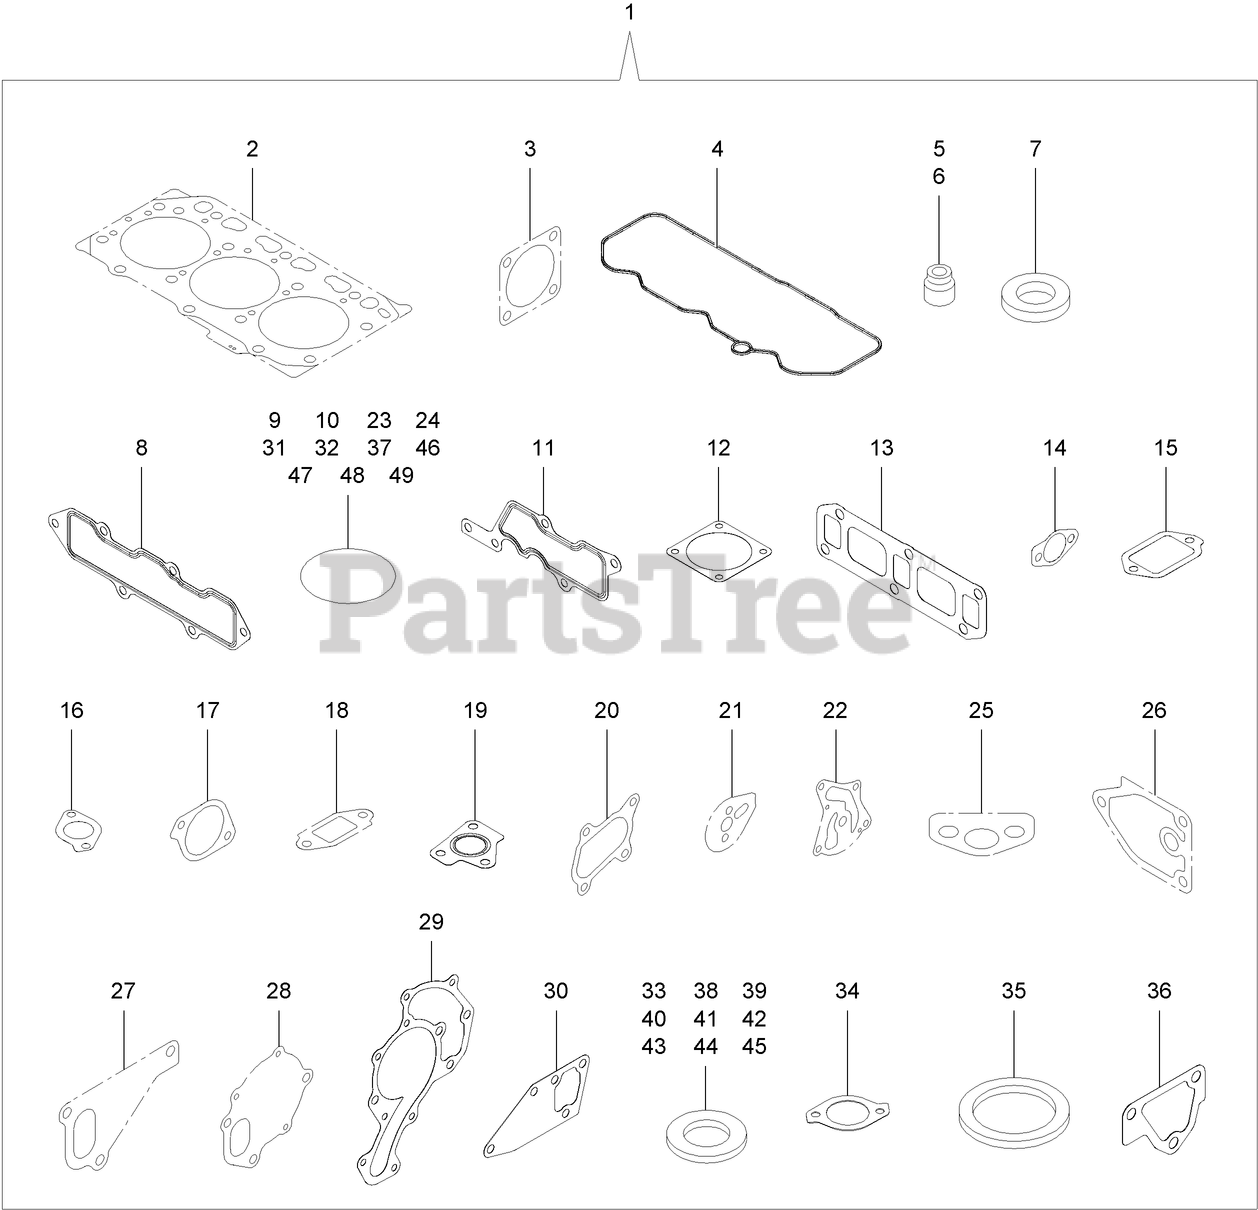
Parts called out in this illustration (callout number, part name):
1	GASKET KIT
2	HEAD GASKET ASM
3	GASKET, PUMP
4	GASKET-COVER, CYLINDER HEAD
5	SEAL-STEM, VALVE
6	SEAL-STEM, VALVE
7	GASKET-INJECTOR
8	GASKET-MANIFOLD, INTAKE
9	O RING-SENSOR, PRESSURE
10	O-RING
11	GASKET-COLLECTOR
12	GASKET-THROTTLE
13	GASKET-MANIFOLD, EXHAUST
14	GASKET-COOLER, E G R
15	GASKET-E G R
16	GASKET
17	GASKET-INTAKE VALVE, E G R
18	GASKET-OUT VALVE, E G R
19	GASKET-IN, T C
20	GASKET-OUT, T C
21	GASKET-IDLE, SHAFT B
22	GASKET
23	O-RING
24	O-RING
25	GASKET
26	GASKET
27	GASKET
28	GASKET
29	GASKET
30	GASKET, WATER PUMP
31	O-RING
32	O-RING
33	GASKET
34	GASKET
35	GASKET
36	GASKET
37	O-RING
38	WASHER-SEAL
39	WASHER-SEAL
40	WASHER-SEAL
41	WASHER-SEAL
42	WASHER-SEAL
43	GASKET
44	GASKET
45	GASKET
46	O-RING
47	O-RING
48	O-RING
49	O-RING, 524031
